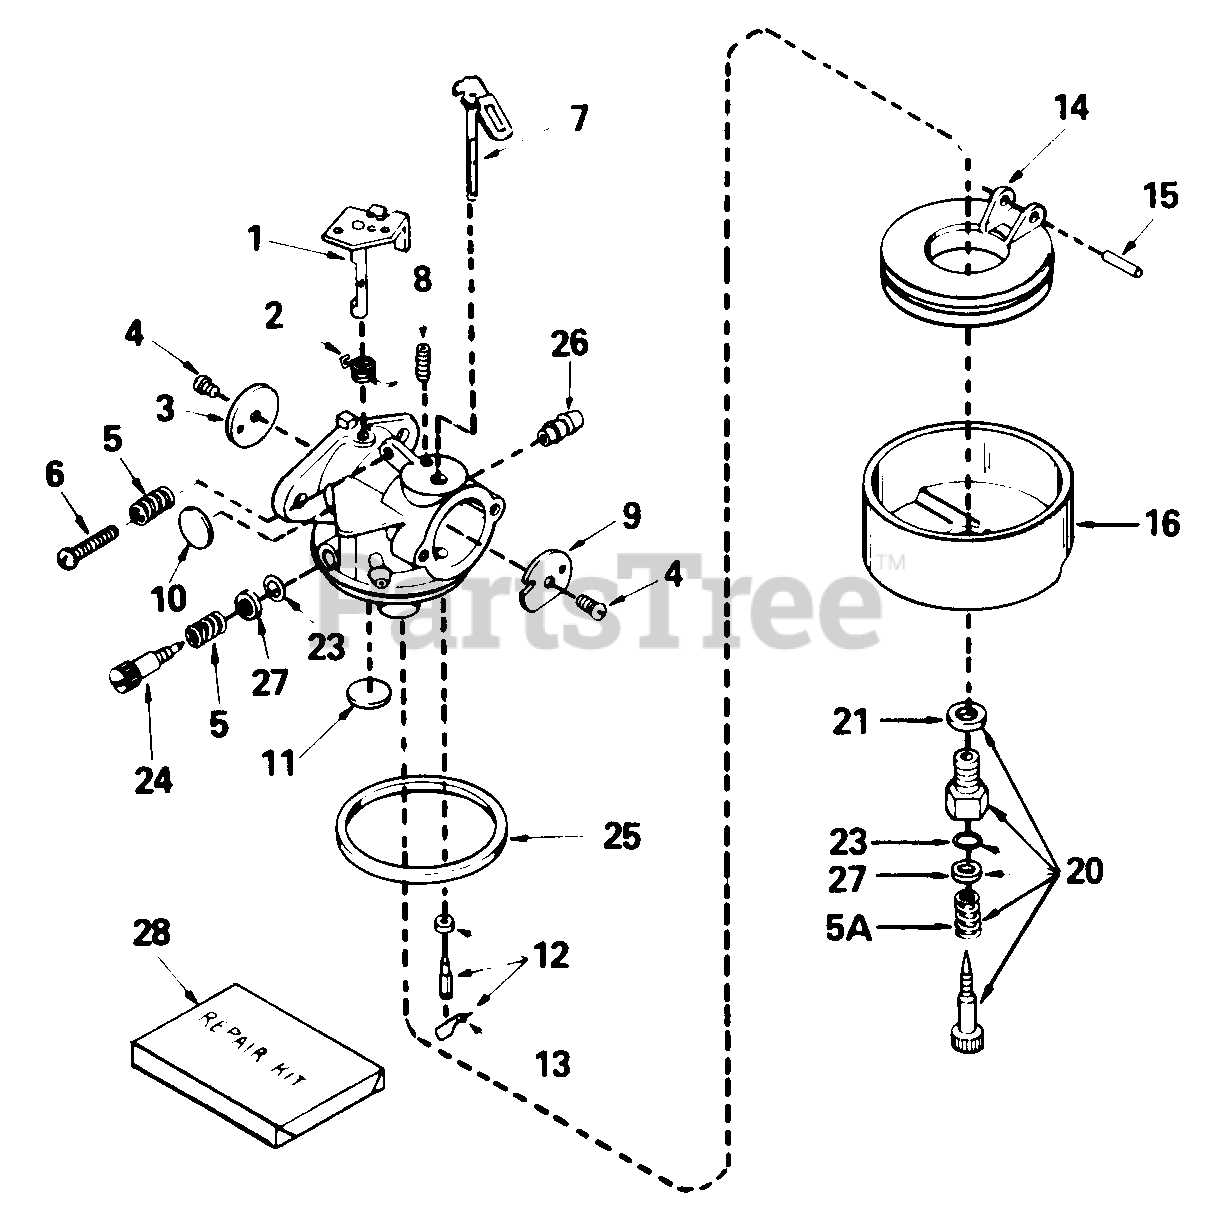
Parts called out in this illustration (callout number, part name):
1	Shaft & Lever Ass'y., Throttle
2	Spring, Throttle Return
3	Shutter, Throttle
4	Screw, Throttle & Choke Shutter
5	Spring, Regulating Screw
5A	Spring, Main Adjustment Screw
6	Screw, Idle Regulating
7	Shaft & Lever Ass'y., Choke
8	Spring, Choke Positioning
9	Shutter, Choke
10	Plug, Welch
11	Plug, Welch
12	Inlet Needle Seat & Clip Ass'y.
13	Clip Inlet Needle
14	Float, arburetor
15	Shaft,Float
16	Bowl, Float
20	Adjustment Screw Ass'y., Main
21	Gasket Bowl-to-Body
23	"O"-Ring, Adjustment Screw
24	Screw, Idle Adjustment
25	Gasket Bowl-to-Body
26	Fitting,Fuel Inlet
28	Repair Kit
